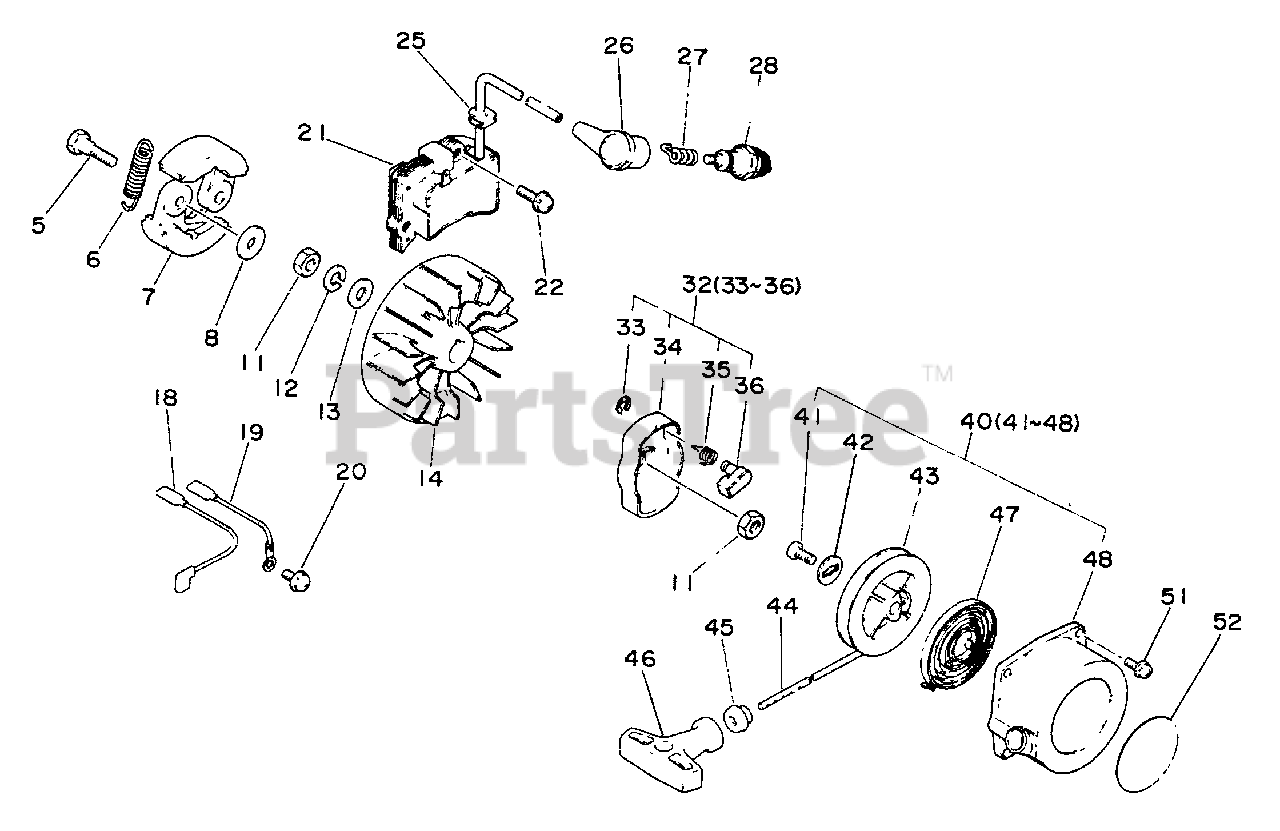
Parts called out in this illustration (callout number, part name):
5	BOLT, CLUTCH
6	SPRING, CLUTCH
7	SHOE, CLUTCH
8	WASHER 6.2×19×1.0
11	NUT 8×1.25
12	WASHER, SPRING 8
13	WASHER 8.5×16×1.2
14	FLYWHEEL
18	LEAD
19	LEAD - GROUND
20	SCREW 5×10
21	COIL, IGNITION
22	SCREW 5×20
26	CAP, SPARK PLUG
27	TERMINAL, SPARK PLUG
28	SPARK PLUG - CJ-7Y
32	PAWL ASSY, STARTER
33	RING, RETAINING - 6
34	CATCHER, PAWL
35	SPRING, RETURN
36	PAWL, STARTER
40	STARTER ASSY
42	WASHER
43	REEL, ROPE
44	ROPE, STARTER 3.5×850
45	GUIDE, ROPE
46	GRIP, STARTER
47	SPRING, RECOIL
48	CASE, RECOIL STARTER
51	SCREW 4×14
52	LABEL, ECHO
